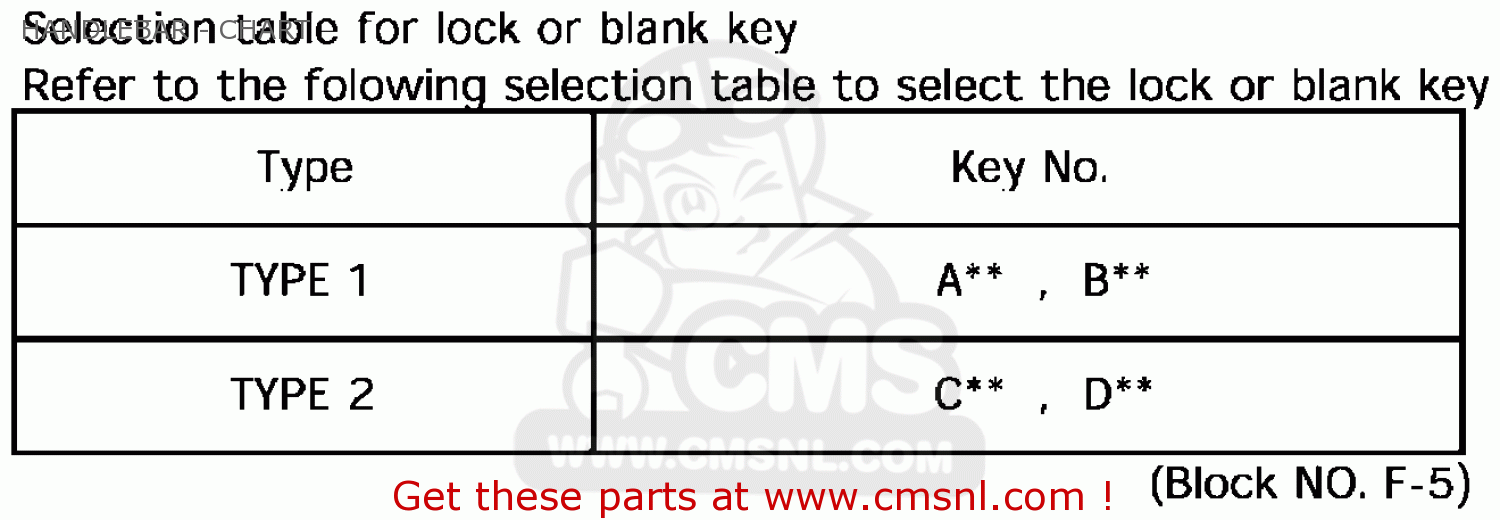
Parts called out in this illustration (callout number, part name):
1	BAND WIRE
2	KEY SET
3	SWITCH ASSY.,COMB
4	KEY,BLANK (NO.1)
5	PIPE,STRG.HANDLE
6	WEIGHT A,HNDL
7	WEIGHT B,HANDLE
8	RUBBER A,HANDLE W
9	SNAPRING,HANDLE W
10	RUBBER,CUSHION
11	BRIDGE,FORK TOP
12	HOLDER,UNDER
13	HOLDER,UPPER
14	CASE,COUPLER LOWE
15	CASE,COUPLER UPPE
16	BOLT,SOCKET,7X32
17	SCREW,OVAL,6X55
18	NUT,STEERING,STEM
19	NUT,FLANGE 8MM
20	WASHER
21	WASHER,CUSHION
22	CAP,SOC.BOLT 8MM
23	SCREW,PAN,6X12
24	SCREW,TAPPING 3X2
25	BOLT,FLANGE,6X16
26	SOCKET BOLT,8X32
